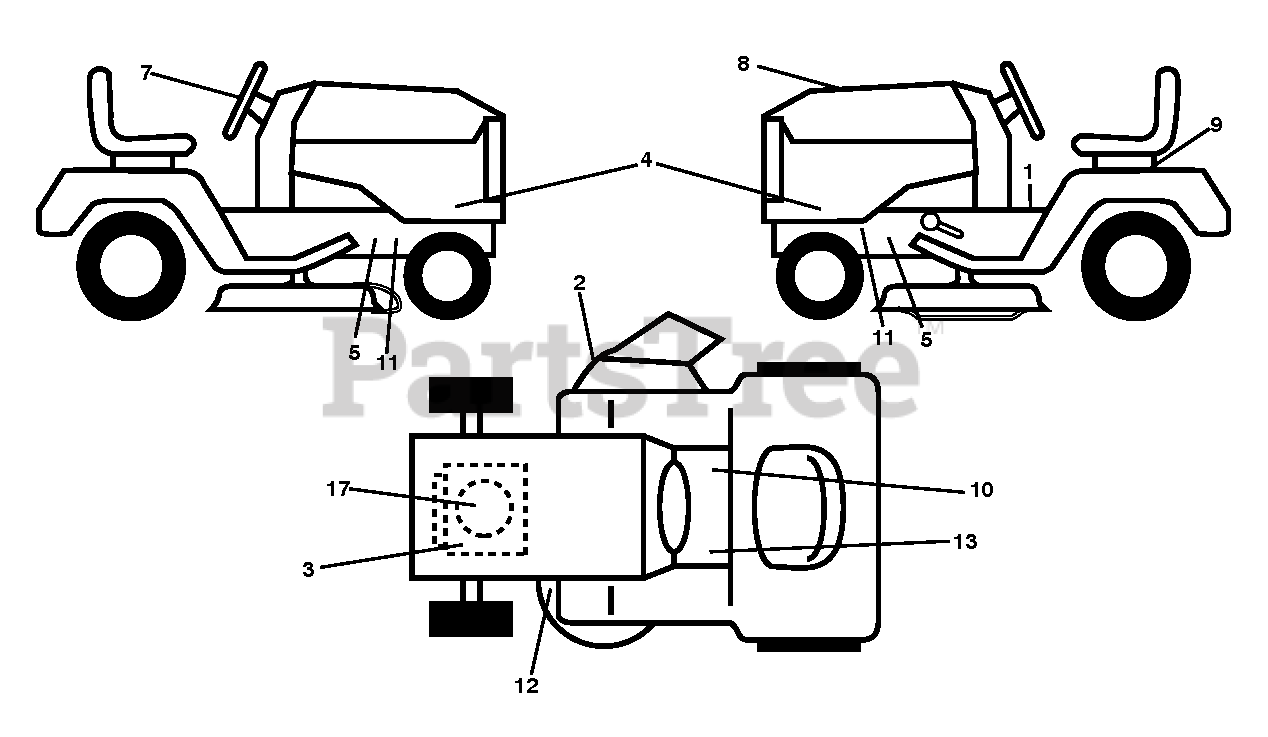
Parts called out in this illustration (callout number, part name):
2	DECAL.WARN.DFLCTRCTF
9	DECAL BTRY SYMBOLS
12	DECAL.V.BELT.30
